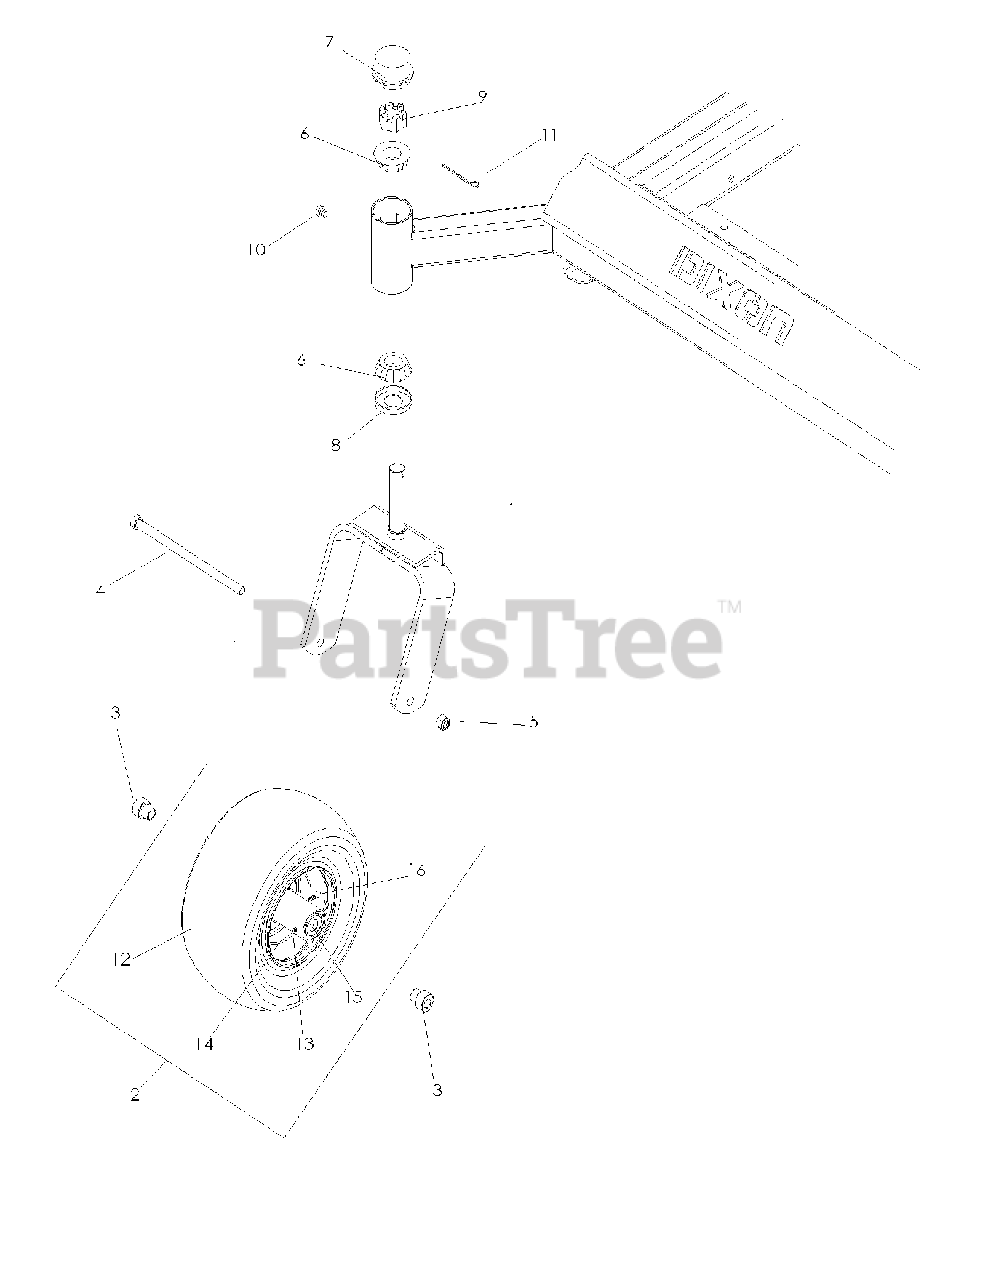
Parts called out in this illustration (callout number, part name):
1	YOKE, CASTER, BLUE
2	FRONT TIRE ASSY
3	AXLE SPACER
4	HEX SCREW 1/2-13 X 9.5 GR5
5	NUT 1/2-13 HEX NYLOC ZD
6	TAPERED ROLLER BRG
7	GREASE CAP
9	NUT 1"C HEX SLOTTED
11	COTTER PIN 1/8 X 2
12	TIRE - SMOOTH 13X6.50-6
13	ZERK
16	VALVE STEM TR-412
